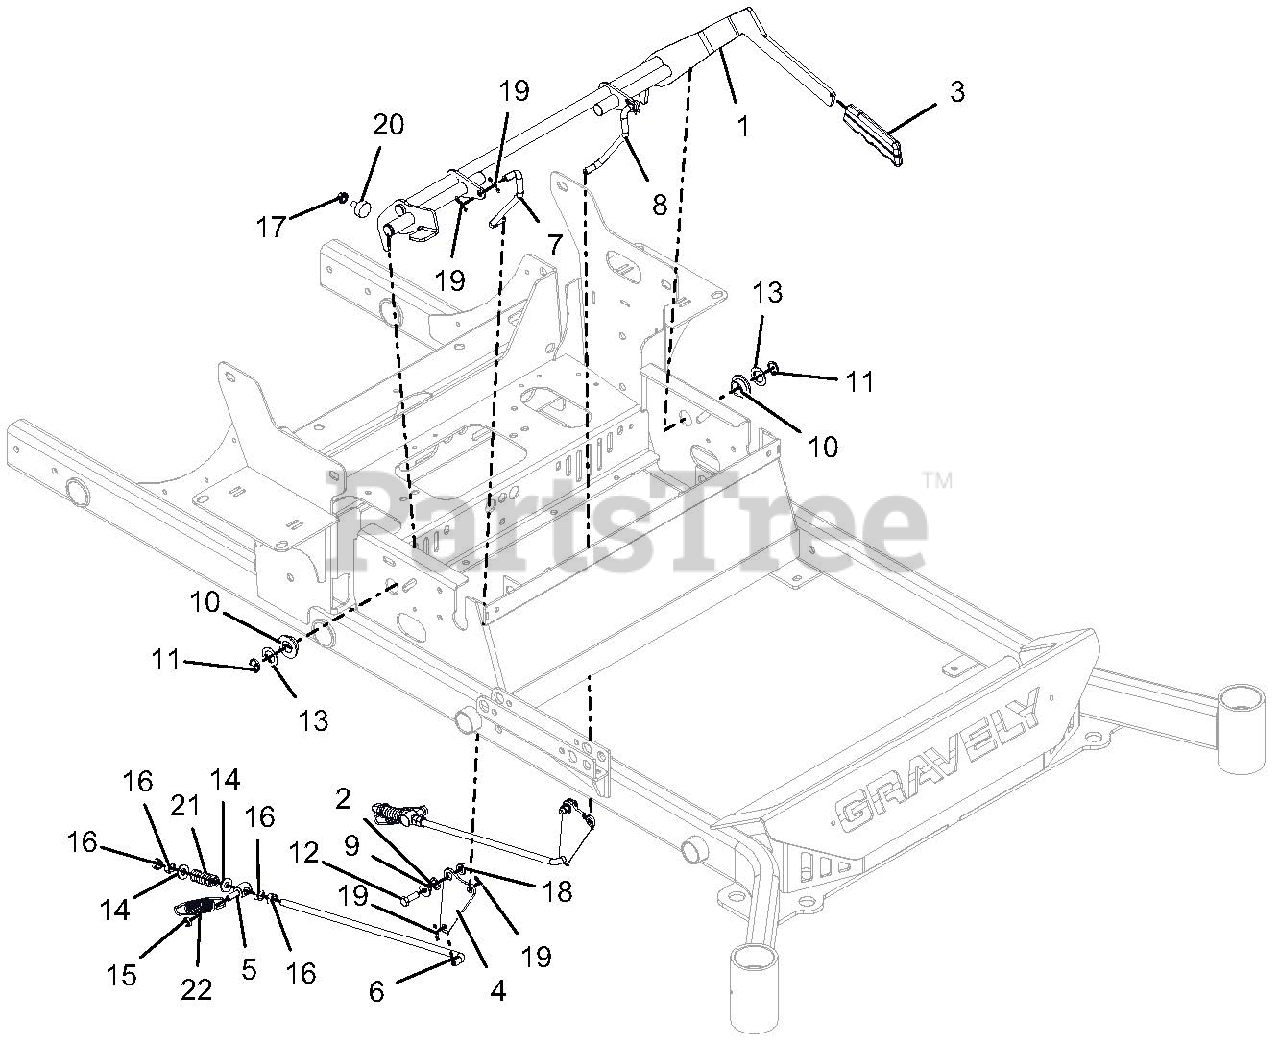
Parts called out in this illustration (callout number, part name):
1	WLDMT, PARKING BRAKE LEVER
2	WAVE WASHER .531X.781X.125 FH
3	GRIP, PARKING BRAKE
4	PLATE, BRAKE PIVOT-BLACK
5	TRUNNION, .31-18
6	ROD, BRAKE ADJ.
7	LINKAGE, RH BRAKE ACTUATING
8	LINKAGE, LH BRAKE ACTUATING
9	BSHG, FLG .32X.500.344X.880
10	BSHG, FLANGE .762 X 1.48 X .44 NYLON
11	RG-RTNG-EXT .750x.078
12	BLT-HEX .31-18X1.00 GR5 YWZC
13	WSHR-HDND-THRST
14	WSHR-FL-STL.38X.875X.083 YWZC
15	@NUT-LK-CTR-JAM .31-18 YWZC
16	NUT-HEX .38-16 YWZC
17	@NUT-SPNLK-FLG .312-18 YWZC
18	NUT, LK-TOP-FLG .312-18 YWZC
19	PIN-HAIR, ENDRIES #25 YWZC
20	BUMPER, RUBBER
21	SPRG, COMPRESSION
22	SPRG, TENSION .105 X .850 X 4.880
